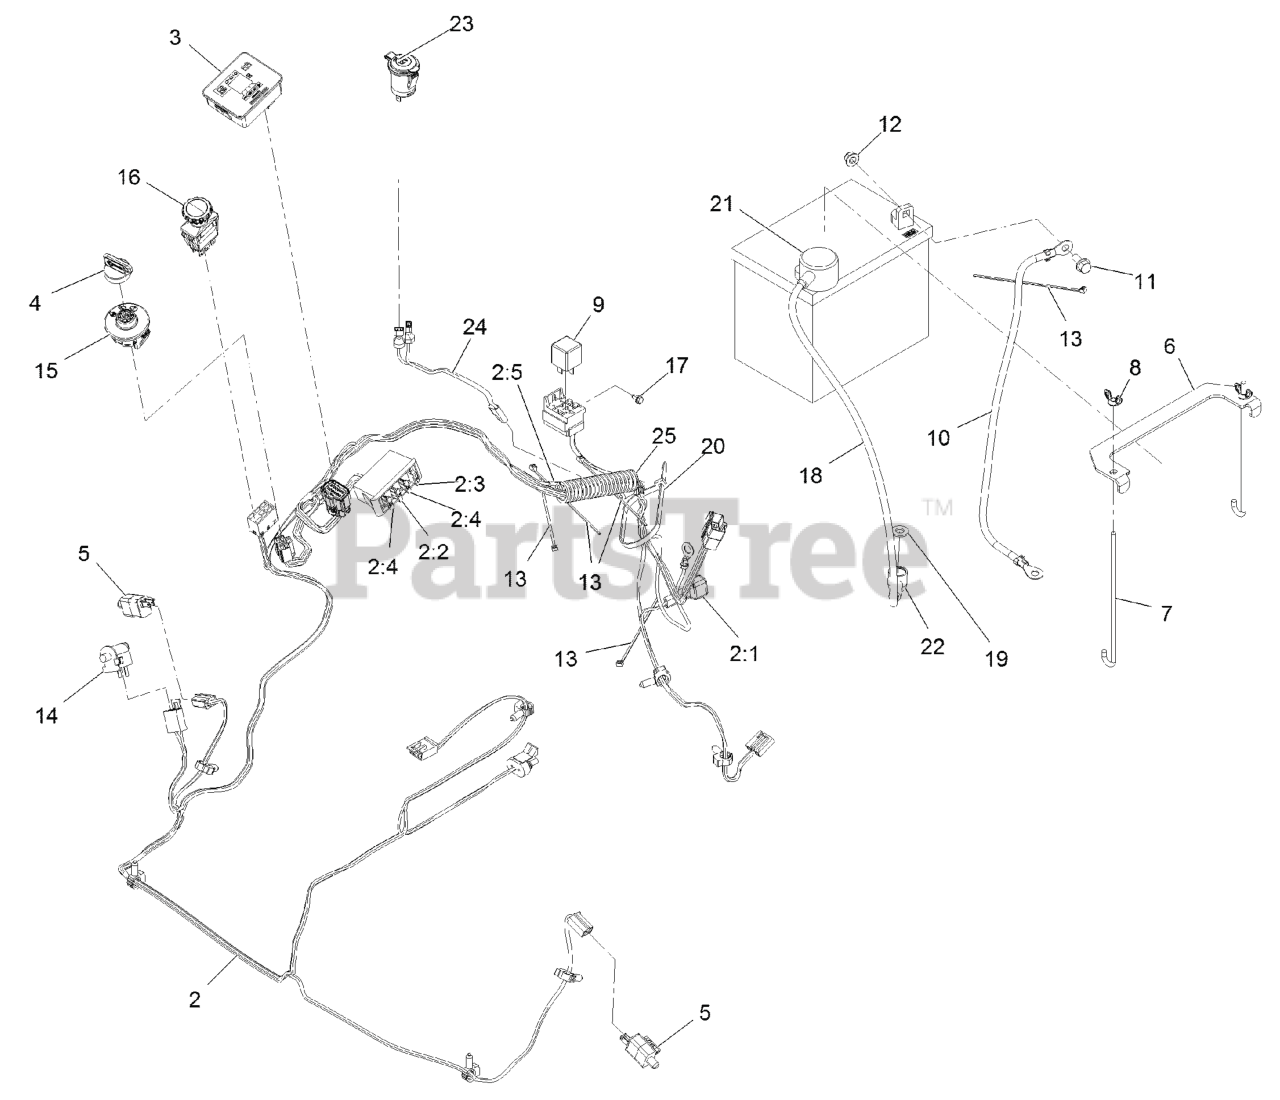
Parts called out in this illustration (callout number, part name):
2	HARNESS-WIRE, MAIN
2:2	FUSE-BLADE, 10 AMP
2:3	FUSE-BLADE, 15 AMP
2:4	FUSE-BLADE, 25 AMP
2:5	CAP-PLUG
3	FUEL/HOUR METER ASM
4	KEYS-IGNITION (SPARE PAIR
4	KEY-IGNITION
6	STRAP-TIE DOWN, BATTERY
7	BOLT-HOLDDOWN
8	WINGNUT
10	CABLE-BATTERY, NEGATIVE
11	SCREW-HHF
12	NUT-HF, NI
13	TIE-CABLE
14	SWITCH-BAIL
15	SWITCH-IGNITION
16	SWITCH-PTO, 10 AMP
17	SCREW-HWH
18	CABLE-BATTERY, POSITIVE
19	WASHER-FLAT
20	TIE-PLASTIC
21	INSULATOR-BATTERY
22	INSULATOR-SOLENOID
23	PORT-POWER, 12V
24	HARNESS, RECEPTACLE 12V
25	COVER-HOSE
